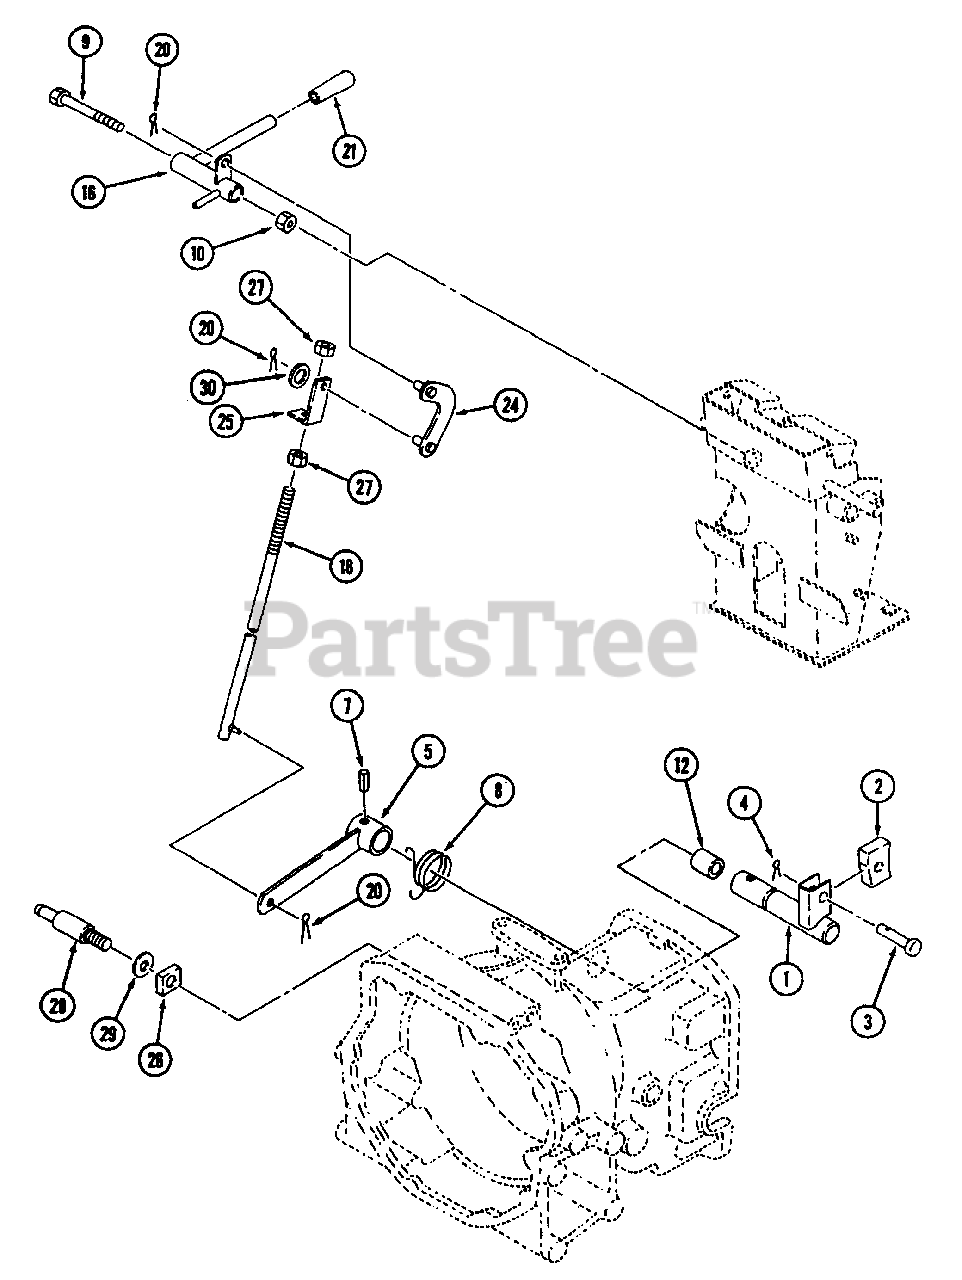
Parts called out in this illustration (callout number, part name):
4	Pin, Split
16	Lever, Craise
20	Pin, Split
